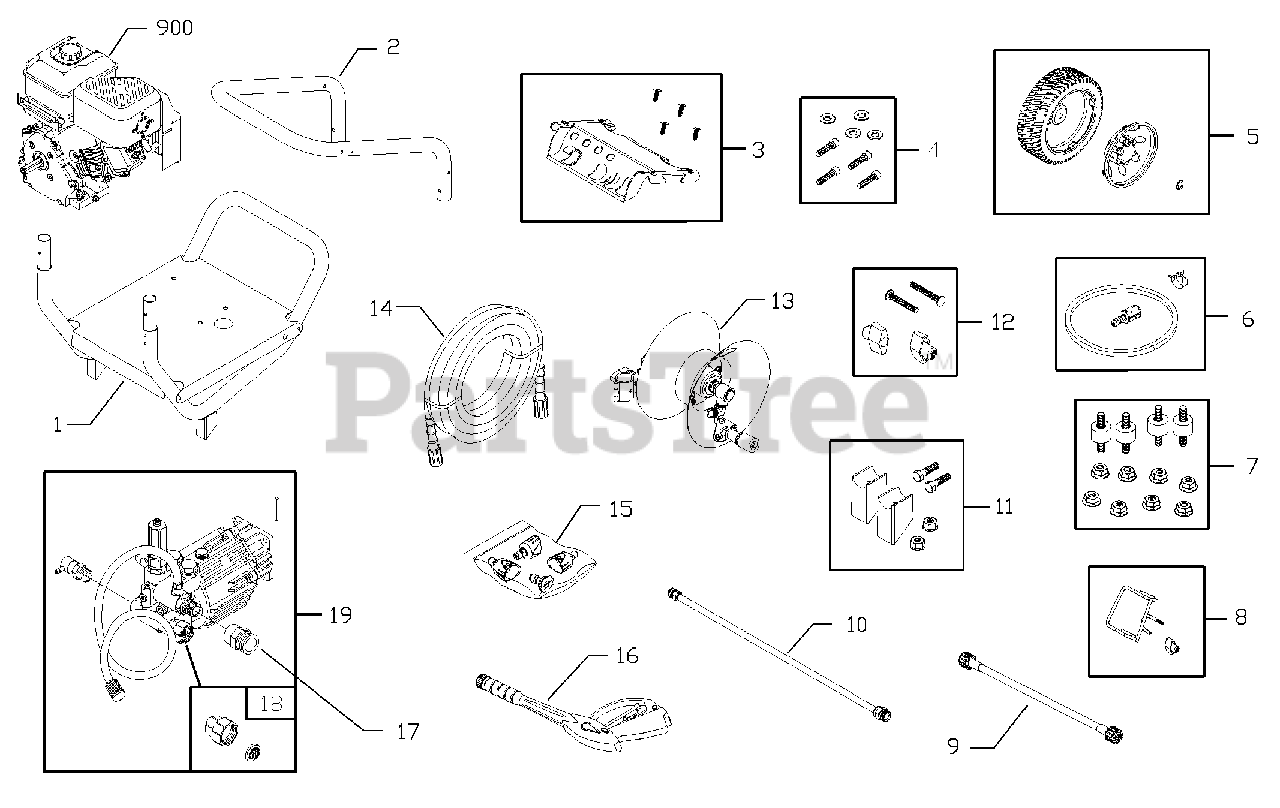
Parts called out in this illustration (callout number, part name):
4	KIT, Hardware, Pump Mounting
6	KIT, Chemical Hose and Filter
7	KIT, Vibration Mount
10	EXTENSION, QC
11	KIT, Vibration Mount
12	KIT, Hardware, Handle
15	KIT, QC Nozzles
16	GUN
18	CONNECTOR, Garden Hose
900	*ENGINE
